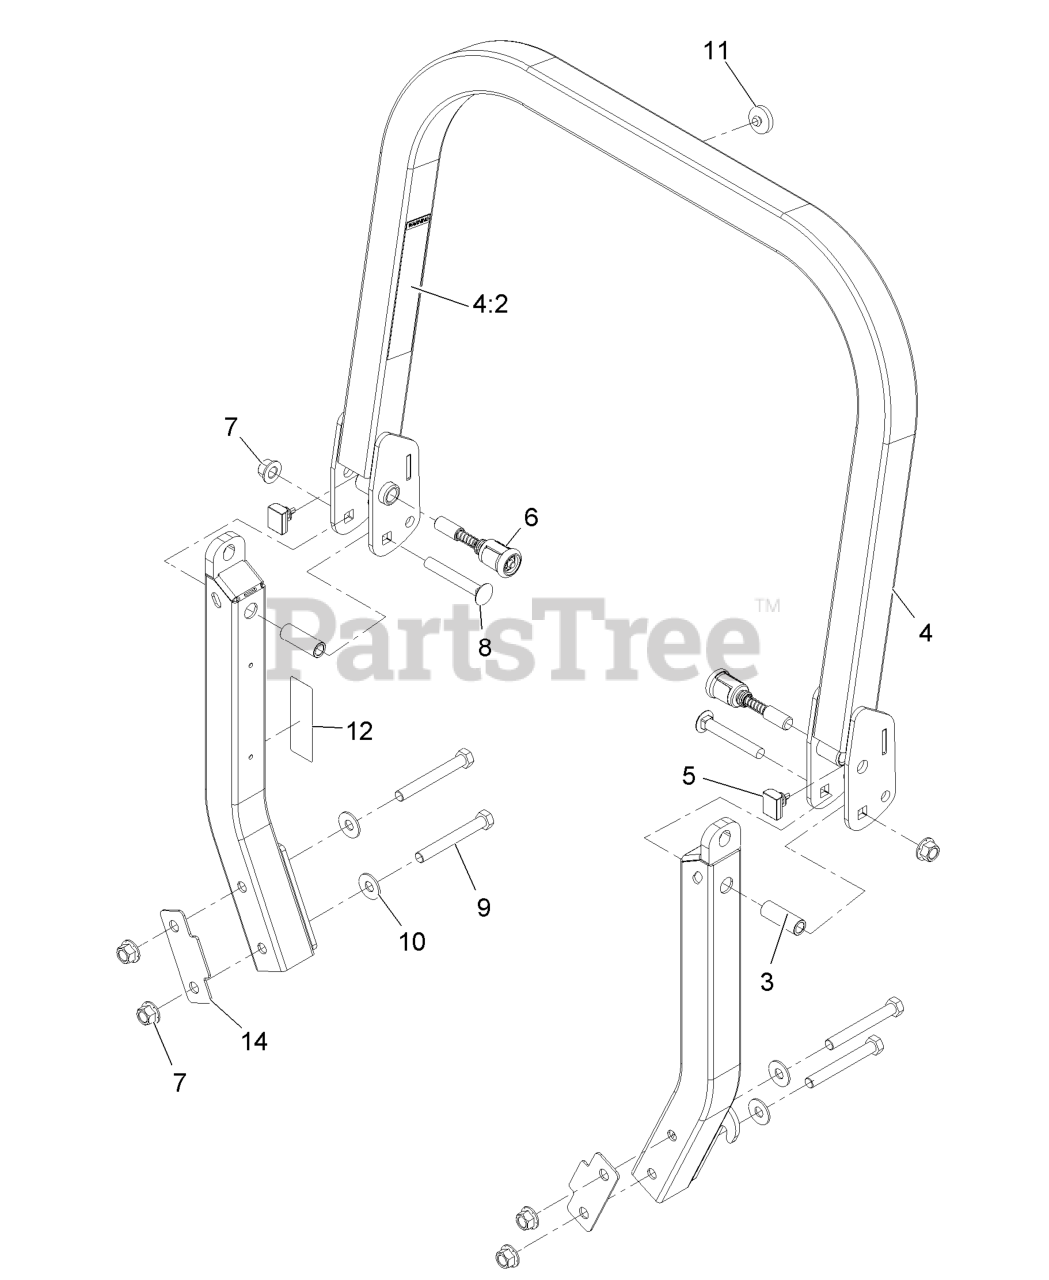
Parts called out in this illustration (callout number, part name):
4	UPPER ROPS ASM
4:2	DECAL-WARNING, FOLDING RO
5	BUMPER-ROPS
6	PIN-SPRING
7	Nut-Lock 1/2-13
8	SCREW-CARR
9	SCREW-HH
10	WASHER-SPRING
11	BUMPER-PUSH-IN, RUBBER
12	DECAL-CAUTION
